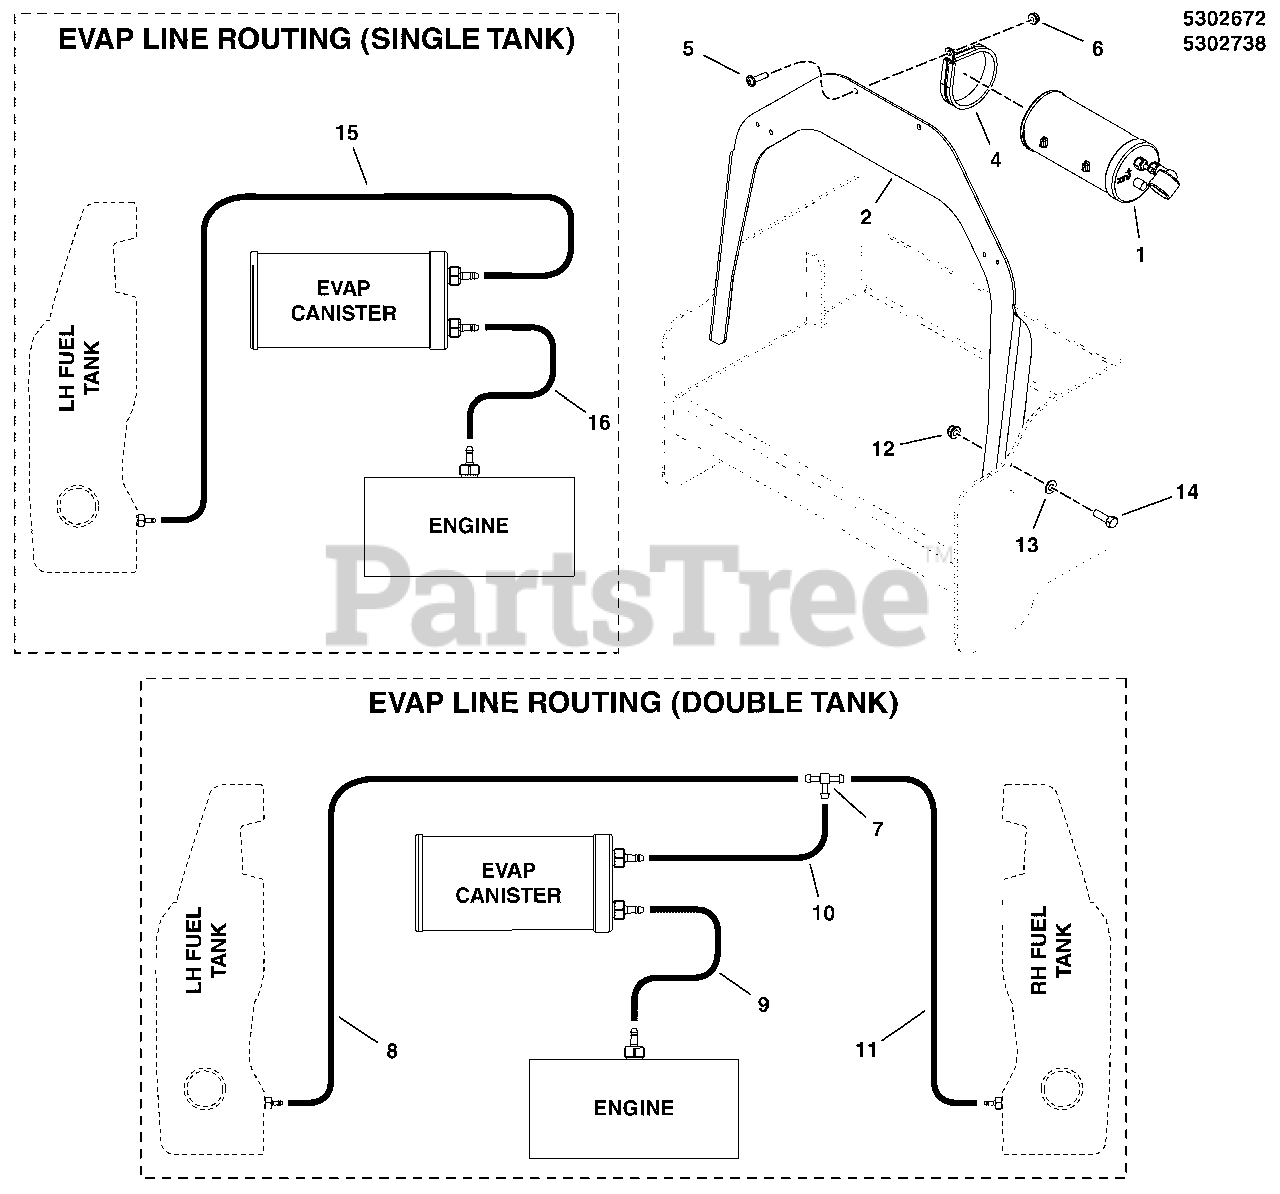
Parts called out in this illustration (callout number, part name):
2	BRACKET, CARB CANISTER, S50X - BLK
4	CLAMP, 3" ID, CUSHIONED, STAINLESS
5	SCREW, 1/4-20 X 3/4 ALLEN BH
6	NUT, 1/4-20 HEX NYLOCK FLANGE
7	FITTING, 3/16" TEE, BARB TYPE, HDPE
8	HOSE, VAPOR, 5MM ID, 43.00 LG
9	HOSE, VAPOR, 5MM ID, 36.00 LG
10	HOSE, VAPOR, 5MM ID, 5.50 LG
11	HOSE, VAPOR, 5MM ID, 11.00 LG
12	NUT, 5/16-18 HEX NYLOCK FLANGE
13	WASHER, 5/16" SAE
14	BOLT, 5/16-18 X 1 GD5 YZ
15	HOSE, VAPOR, 5MM ID, 36.50 LG
16	HOSE, VAPOR, 5MM ID, 29.50 LG
